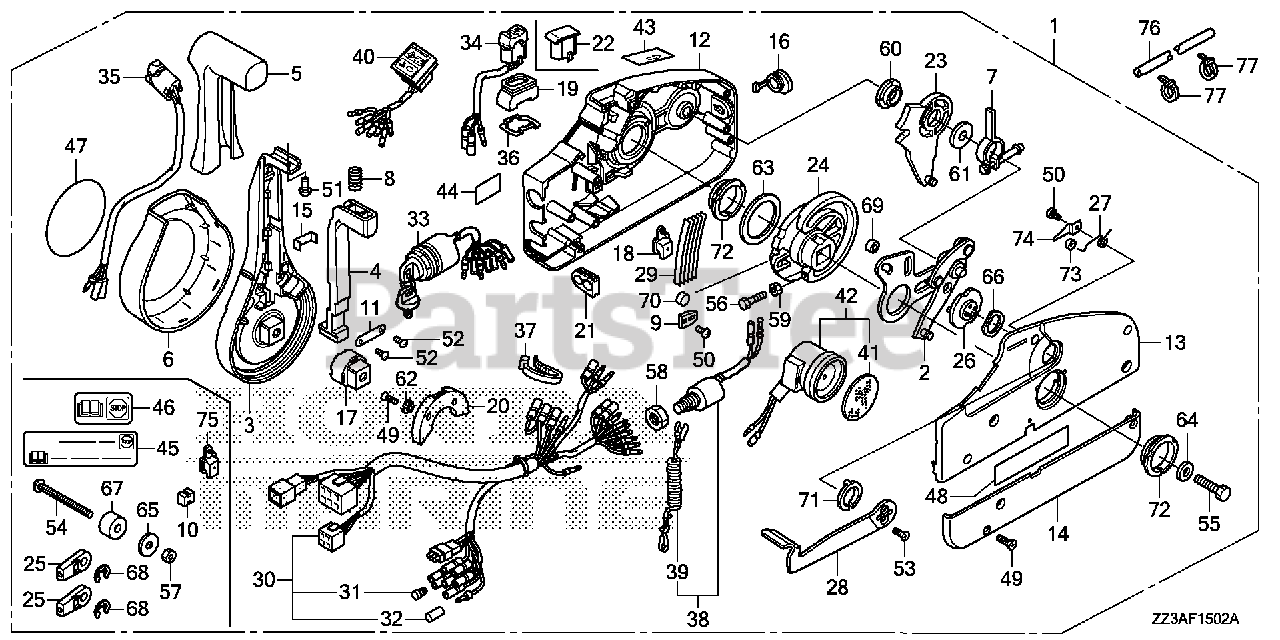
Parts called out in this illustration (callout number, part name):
1	BOX ASSY., REMOTE CONTROL (NHK MEC)
1	BOX ASSY., REMOTE CONTROL (TROLLING CONTROL)(NHK MEC)
2	PLATE ASSY.
3	LEVER, HAND
4	ARM, NEUTRAL LOCK
5	GRIP
6	COVER, LEVER
7	ARM ASSY., BRAKE
8	SPRING (2)
9	CLIP, DETENT
10	SPACER (1) (LOOSE PARTS)
11	BRACKET
12	HOUSING, FR.
13	HOUSING, RR.
14	PANEL, BACK
15	BRACKET, WIRE CLAMP
16	CAP, RUBBER
17	ADJUSTER
18	COVER, POWER TRIM-TILT WIRE
19	SEAL, RUBBER
20	HOLDER, NEUTRAL LOCK
21	GROMMET, WIRE (14)
22	CAP, TROLLING CONTROL SWITCH BLANK
23	GEAR ASSY., SHIFT
24	GEAR, DRIVE
25	TERMINAL, CABLE (LOOSE PARTS)
26	DRUM ASSY., FREE THROTTLE
27	SPRING (1)
28	LEVER, FREE THROTTLE
29	SPRING, DETENT
30	CABLE ASSY., REMOTE CONTROL (B)
30	CABLE ASSY., REMOTE CONTROL (B)(TROLLING CONTROL)
31	PLUG, CONNECTOR (INNER) (TROLLING CONTROL)
32	PLUG, CONNECTOR (OUTER)
33	SWITCH ASSY., COMBINATION
34	SWITCH ASSY., TROLLING CONTROL
35	SWITCH ASSY., POWER TRIM-TILT
36	PLATE, SWITCH
37	BAND, WIRE
38	SWITCH ASSY., EMERGENCY STOP
39	WIRE, EMERGENCY
40	LAMP ASSY., INDICATION
41	PLATE, TURN SIGNAL BUZZER
42	BUZZER, WARNING
43	MARK, FAST IDLE
44	MARK, EMERGENCY STOP (US)
45	MARK, EMERGENCY STOP (US) (LOOSE PARTS)
47	MARK, EMBLEM
48	LABEL, SIGP
49	SCREW (5X18)
50	SCREW (4X6)
51	SCREW (5X10)
52	SCREW (4X10)
53	SCREW (5X12)
54	SCREW (6X90) (LOOSE PARTS)
55	BOLT (8X50)
56	BOLT (5X25)
57	NUT (6MM) (LOOSE PARTS)
58	NUT, HEX. (16MM)
59	NUT (5MM)
60	BEARING (1)
61	WASHER (3)
62	WASHER (4)
63	WASHER (5)
64	WASHER (8MM)
65	WASHER (7) (LOOSE PARTS)
66	WASHER, WAVE
67	SPACER (2) (LOOSE PARTS)
68	E-RING (6MM) (LOOSE PARTS)
69	ROLLER, DRIVE GEAR CAM
70	ROLLER
71	BEARING (2)
72	BEARING (3)
73	ROLLER, FREE THROTTLE
74	CLIP, ROLLER
75	COVER, POWER TRIM-TILT WIRE (LOOSE PARTS)
76	TUBE, CORRUGATE (28MM)
77	BAND, SELF-LOCK
